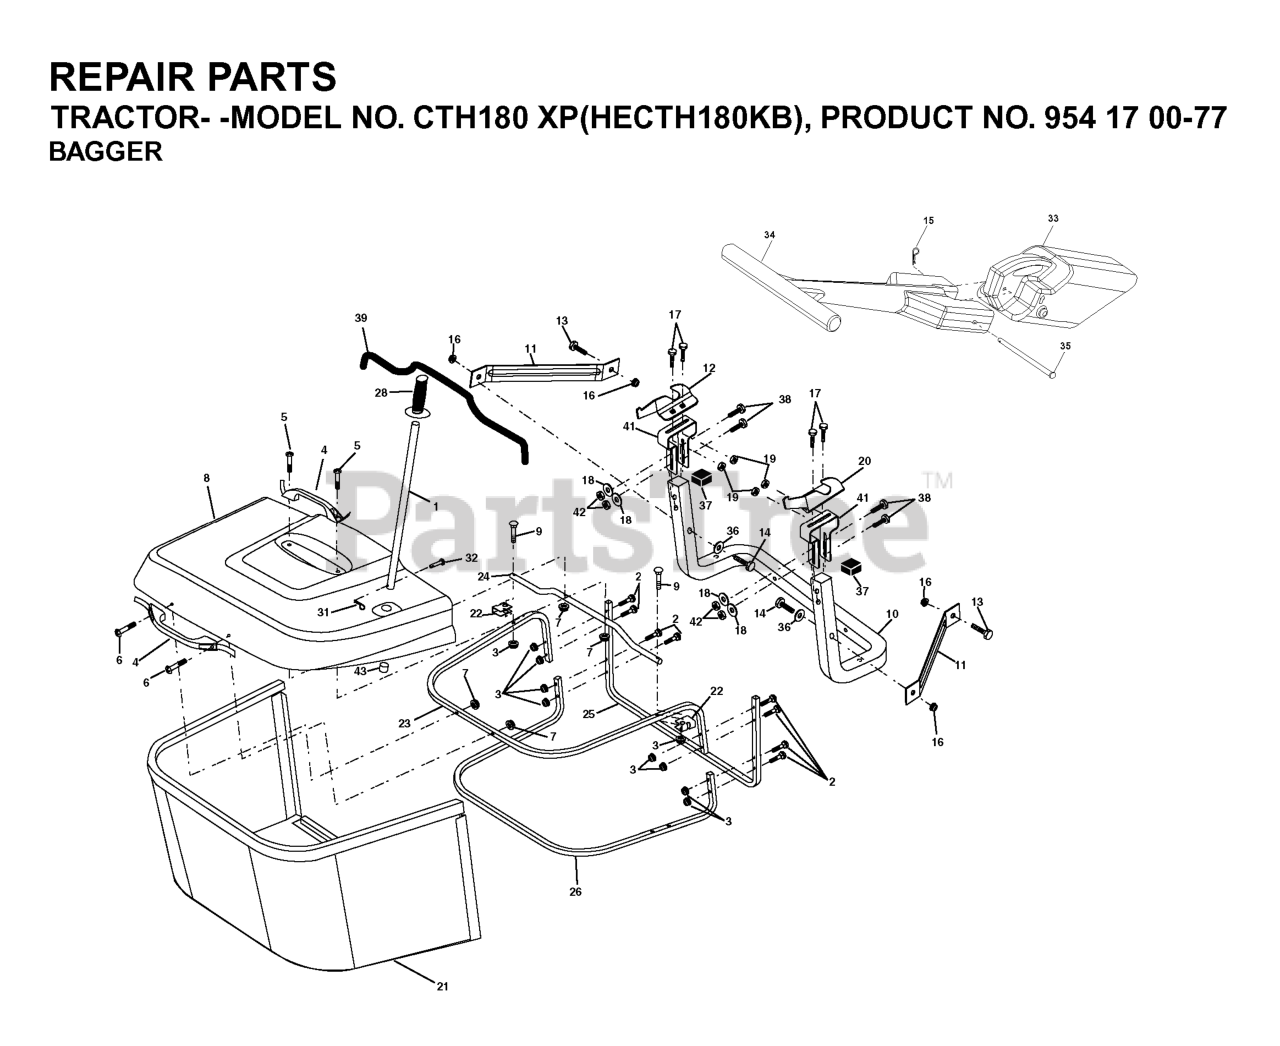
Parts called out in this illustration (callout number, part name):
1	TUBE HANDLE
2	Bolt Carriage 1/4-20 x 2.0 Gr.5
3	NUT T
4	HANDLE.BAGGER.W/LVRS.BLK.CRD
5	SCREW.PAN.HEAD
6	REPL BY 532 75 00-29
8	COVER.PNT.BGR.CRD.WSLOTS.MS668
9	Bolt Carriage 1/4-20 x 2.25d x Gr.5
10	TUBE
11	BRACKET.SUPPORT.UPPER.BAG.CRD
14	BOLT-HEX EAK
15	RETAINER-SPRNG RB
16	NUT LOCK FLG 3/8-16 UNC
17	RP BOLT 5/16-18 X3/4 ZN/YEL GR
18	WASHER M
19	NUT LOCK HEX FLANGE 5/16-18
20	BRACKET
21	GRASS BAG
22	BRKT.SIDE.BAG.CRD
23	TUBE.UPPER.BAG.CRD
24	TUBE.PIVOT.BAG.CRD.BLACK
26	TUBE.LOWER.BAG.CRD
28	GRIP.HANDLE.BLACK
31	RETAINER CLIP
32	RIVET,DRILLED
33	MULCH PLUG, CTH150
34	HANDLE.MULCHER.92.CRD (2 2)
36	WASHER
37	Plug Support Bagger CRD
38	BOLT.5/16-18X2.5
39	SEAL.TRIM.37'
41	BRKT.VERT.ADJ.BAGGER.CRD
42	NUT.71038.31-18.HEX.NYLOCK
43	PLUG, TUBING END
